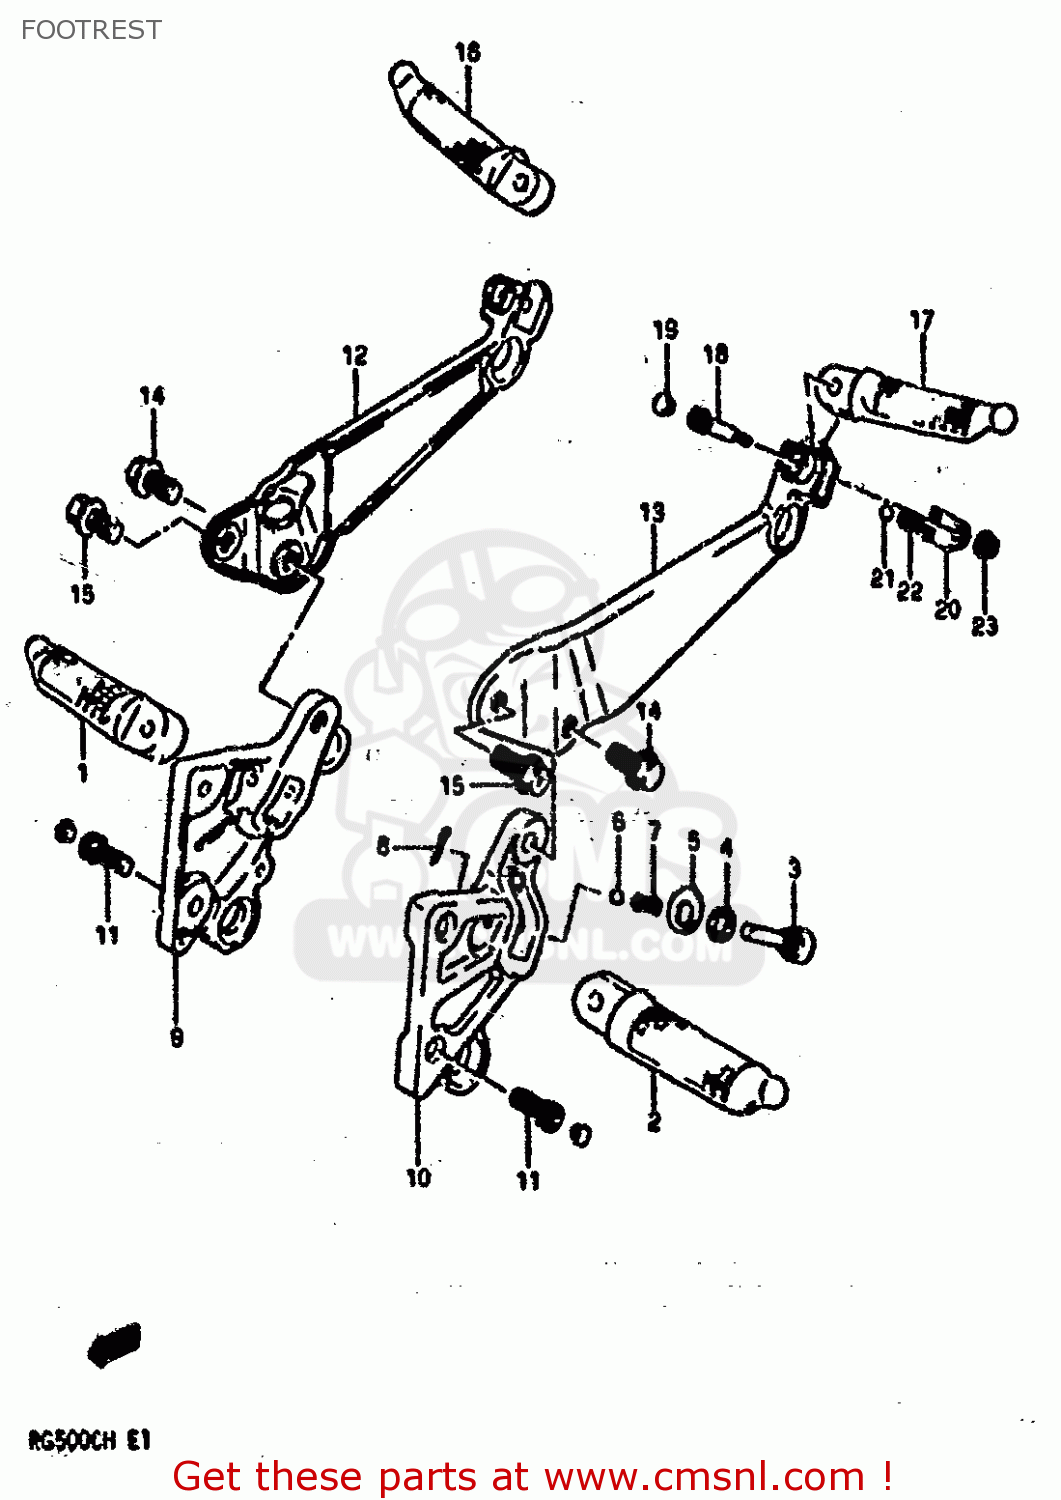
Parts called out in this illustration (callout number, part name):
1	FOOTREST ASSY,FR,R
2	FOOTREST ASSY,FR,L
3	BOLT, FRONT FOOTREST
4	WASHER,LOCK
5	PLATE,SPRING STOP FR
6	BALL
7	SPRING
8	PIN
9	BRACKET,FOOTREST RH
10	BRACKET,FOOTREST LH
11	BOLT
12	BRACKET,PILLION FOOTREST RH
13	BRACKET,PILLION FOOTREST LH
14	BOLT,LOWER
15	BOLT,UPPER
16	FOOTREST ASSY
17	FOOTREST ASSY
18	BOLT,PILLION FOOTREST
19	CAP(OD:10)
20	PLATE,SPRING STOP,R
21	BALL
22	SPRING
23	NUT
